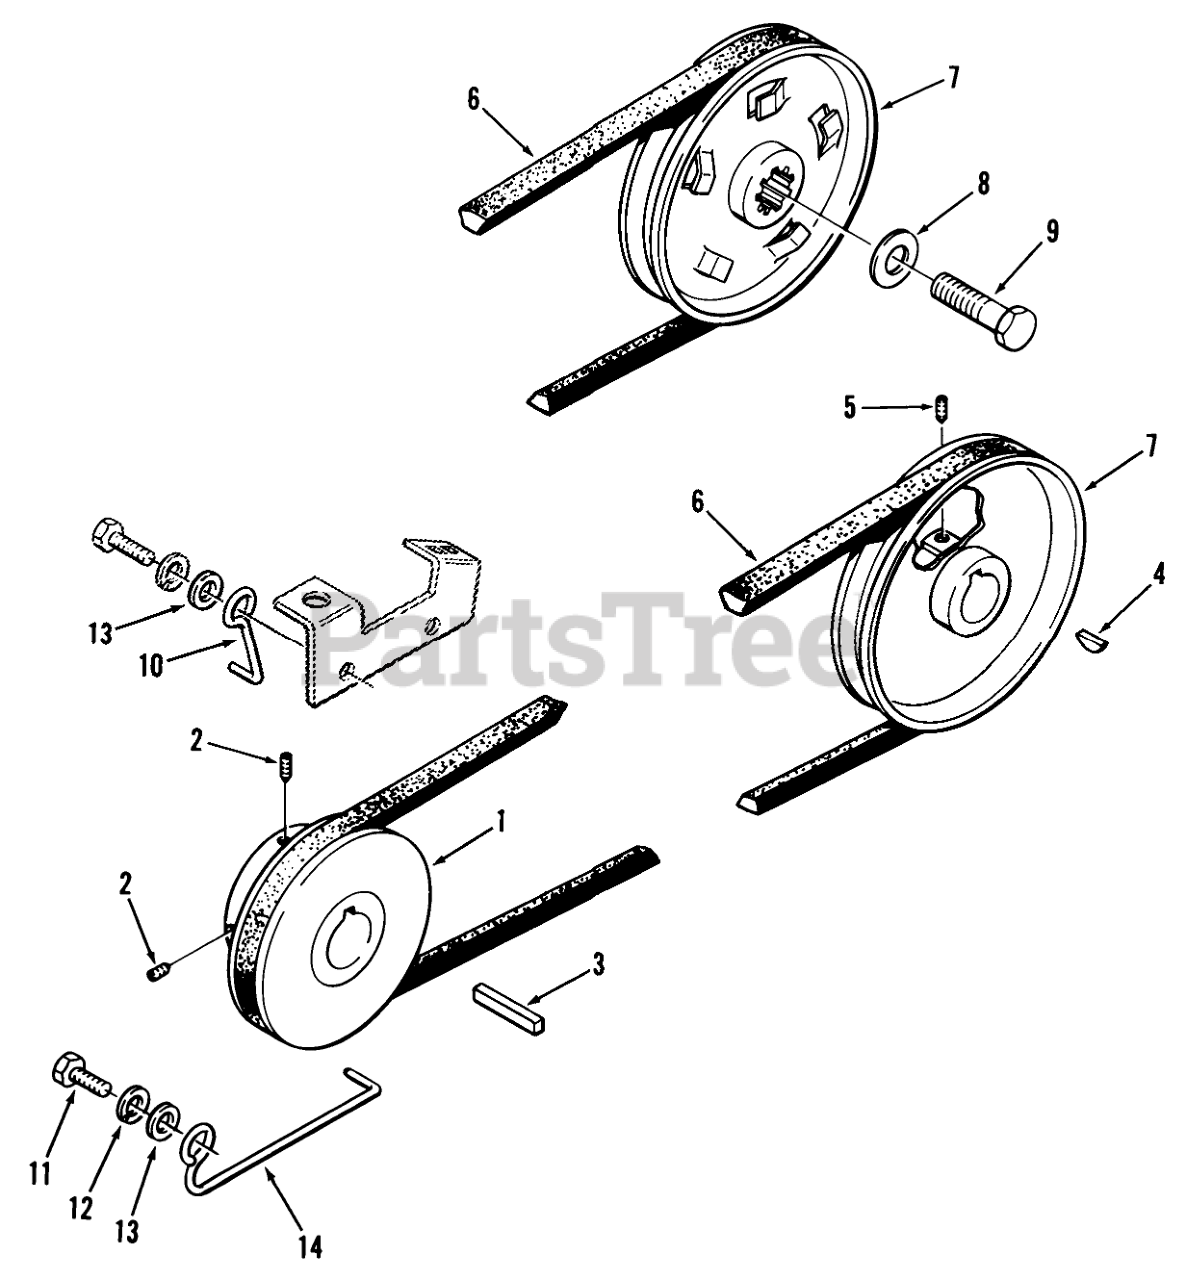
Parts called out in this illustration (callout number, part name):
1	PULLEY-ENGINE
1	PULLEY
1	Engine Drive Pulley
2	Set Screw
4	KEY-HI PRO
5	Set Screw
6	V BELT
6	V-BELT
6	Belt-Drive
7	Transmission Drive Pulley
7	PULLEY-TRANSMISSION
8	WASHER
9	Bolt
10	Belt Guide-Top
11	7/16-14 x 1 1/4 Bolt
11	Bolt
12	LOCKWASHER
13	WASHER
13	Washer
14	Belt Guide-Bottom
